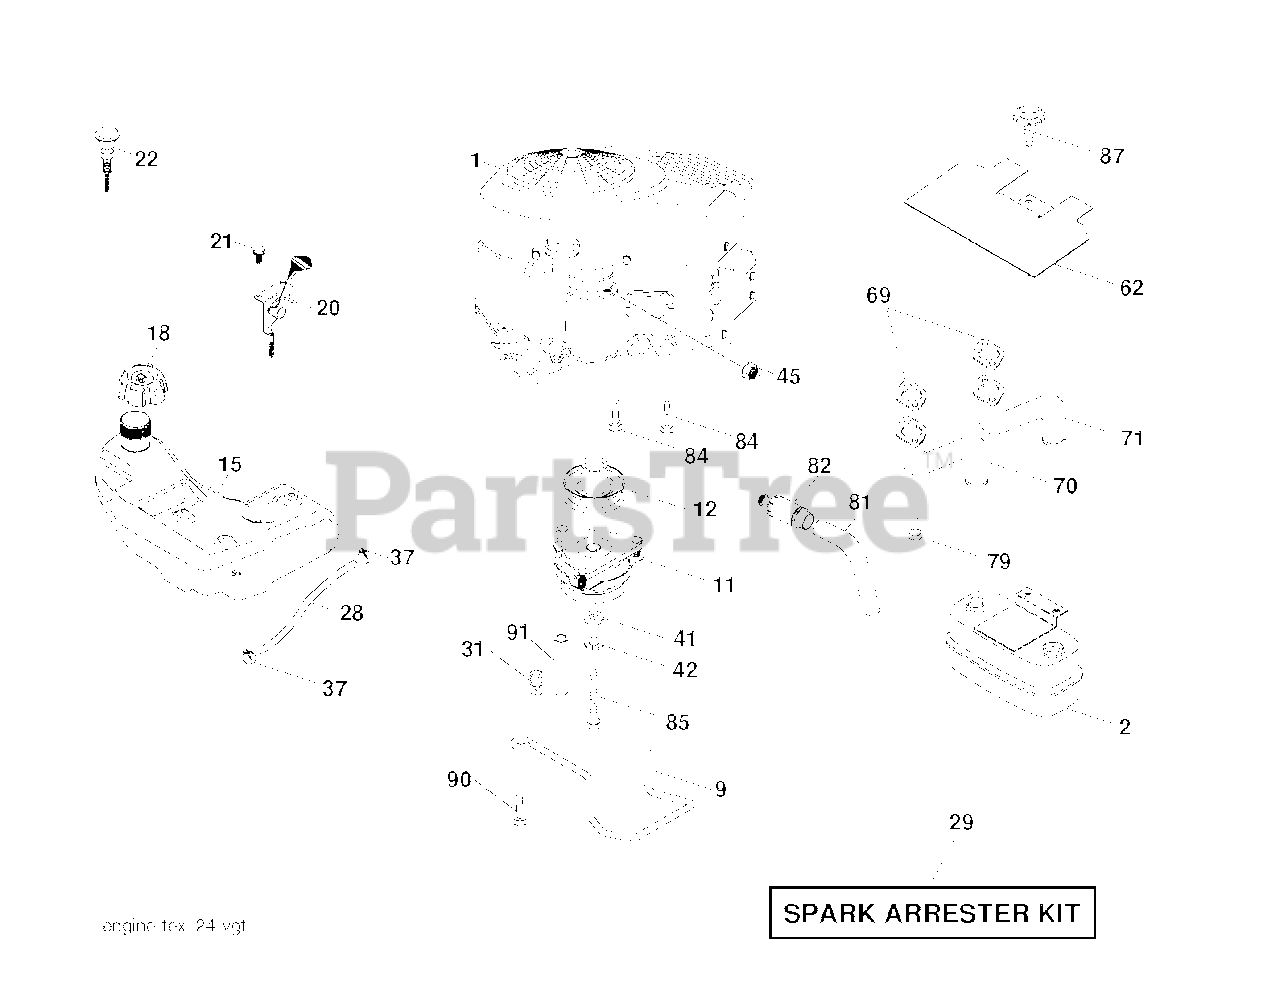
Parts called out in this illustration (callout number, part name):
2	MUFFLER.TWIN.CYL.LOW.TONE
9	KEEPER.BELT.ENGINE.3.25
11	CLUTCH ELECTRIC
12	PULLEY.ASM.ENGINE.1-1/8X3-1/4
15	TANK.FUEL.4GAL
18	CAP.ASM.FUEL.TANK.3"BL
20	THROTTLE CABLE
21	SCREW
22	CONTROL CHOKE
29	ARRESTER SPARK (OPTIONAL)
31	PUSH CLIP
37	HOSE CLAMP
42	LOCKWASHER
45	NUT
62	RP SHIELD HEAT MUFFLER
69	GASKET.MUFFLER
70	TUBE MANIFOLD LH
71	EXHAUST TUBE RH
79	SCREW.SOCKET.HEAD.5/16-18
81	TUBE, DRAIN OIL ASM.
82	PLUG DRAIN OIL EASY
84	SCREW.3/8-16
85	BOLT HEX 7/16-20 X 3.75 GR. 5
87	BOLT.5/16-18UNCX1.W/SEMS.BLK
90	SCREW 3/8-16X1
91	BUSHING.1.375OD
